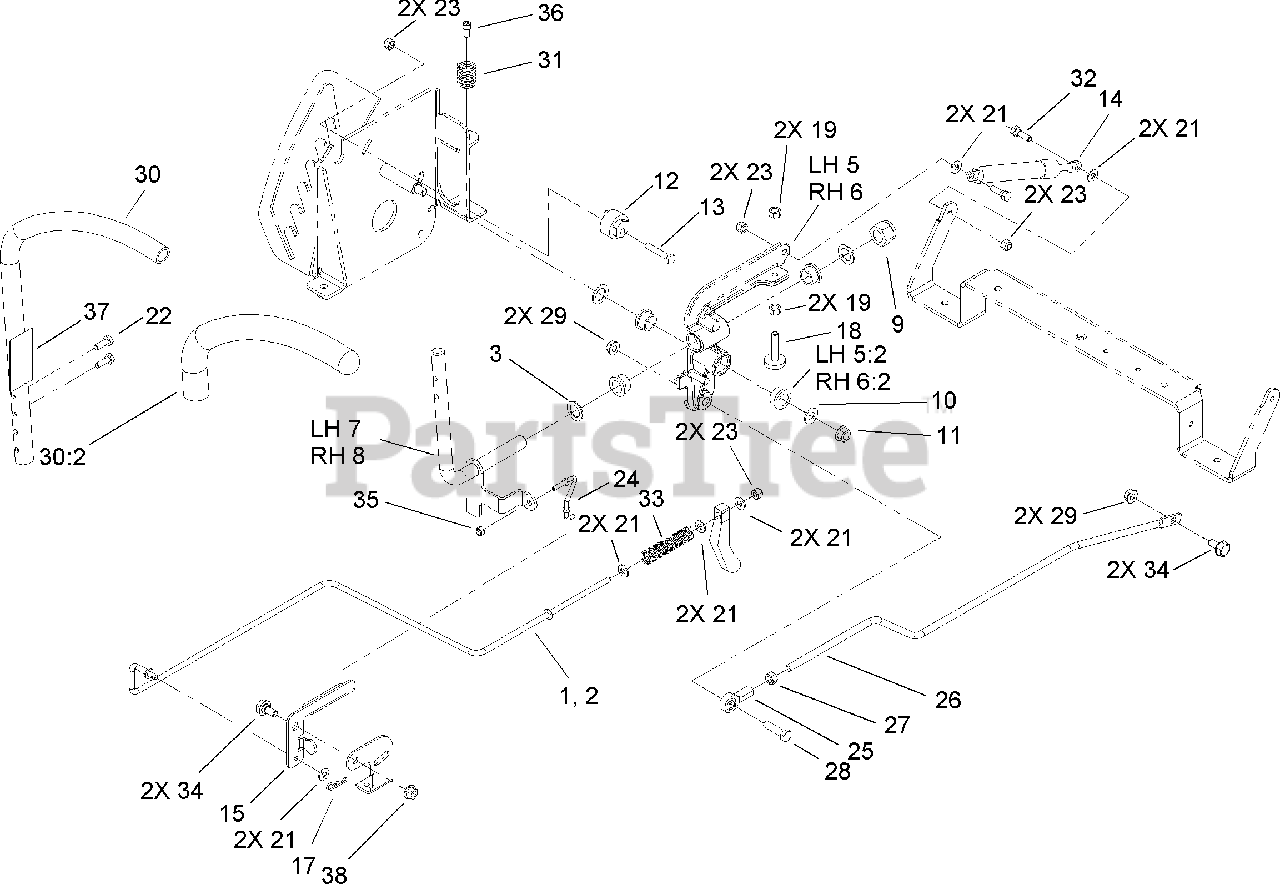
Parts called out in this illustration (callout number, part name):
1	ROD-BRAKE, LH
2	ROD-BRAKE, RH
3	WASHER-THRUST
5	LH ACTIVATOR ARM ASM
6	RH ACTIVATOR ARM ASM
7	LH PIVOT SHAFT ASM
8	RH PIVOT SHAFT ASM
9	NUT-LOCK, NI
10	WASHER-FLAT
11	NUT-LOCK, NI
12	ECCENTRIC
13	SCREW-HH
14	Damper-Control, Motion
15	BELLCRANK
18	STOP-ADJUSTMENT
19	NUT-HEX
21	WASHER-FLAT
22	SCREW-HH
23	NUT-LOCK, NI
24	LINK-BRAKE
25	BALLJOINT-RH
26	ROD-HYDRO
27	NUT-HEX
28	SCREW-HH
30	HANDLE ASM
31	SPRING-COMPRESSION
32	BOLT-SHOULDER
33	SPRING-COMPRESSION
34	BOLT-SHOULDER
35	NUT-LOCK
36	SCREW-HSH
